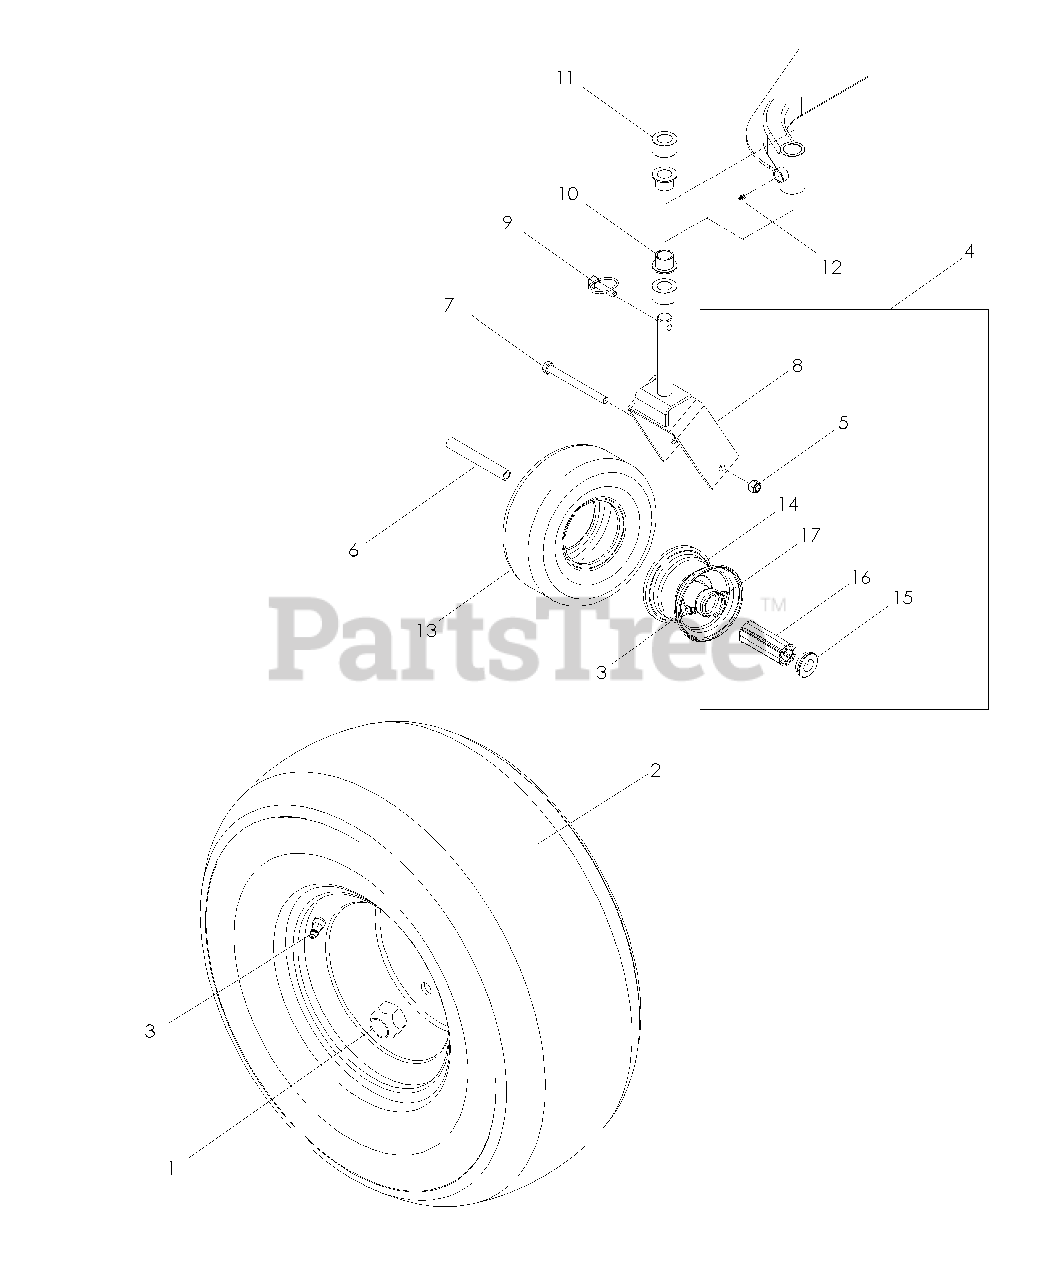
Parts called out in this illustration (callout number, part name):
2	WHEEL ASSM, REAR
3	VALVE STEM
4	CASTER ASSEMBLY
5	NUT 1/2-13 HEX NYLOC
7	HCS 1/2-13 x 5 1/2
8	FORK, CASTER
9	LYNCH PIN, 7/16
10	BUSHING, CASTER
12	ZERK
13	TIRE
15	BEARING, FLANGE
16	BEARING, ROLLER, 3 1/4
17	ZERK
